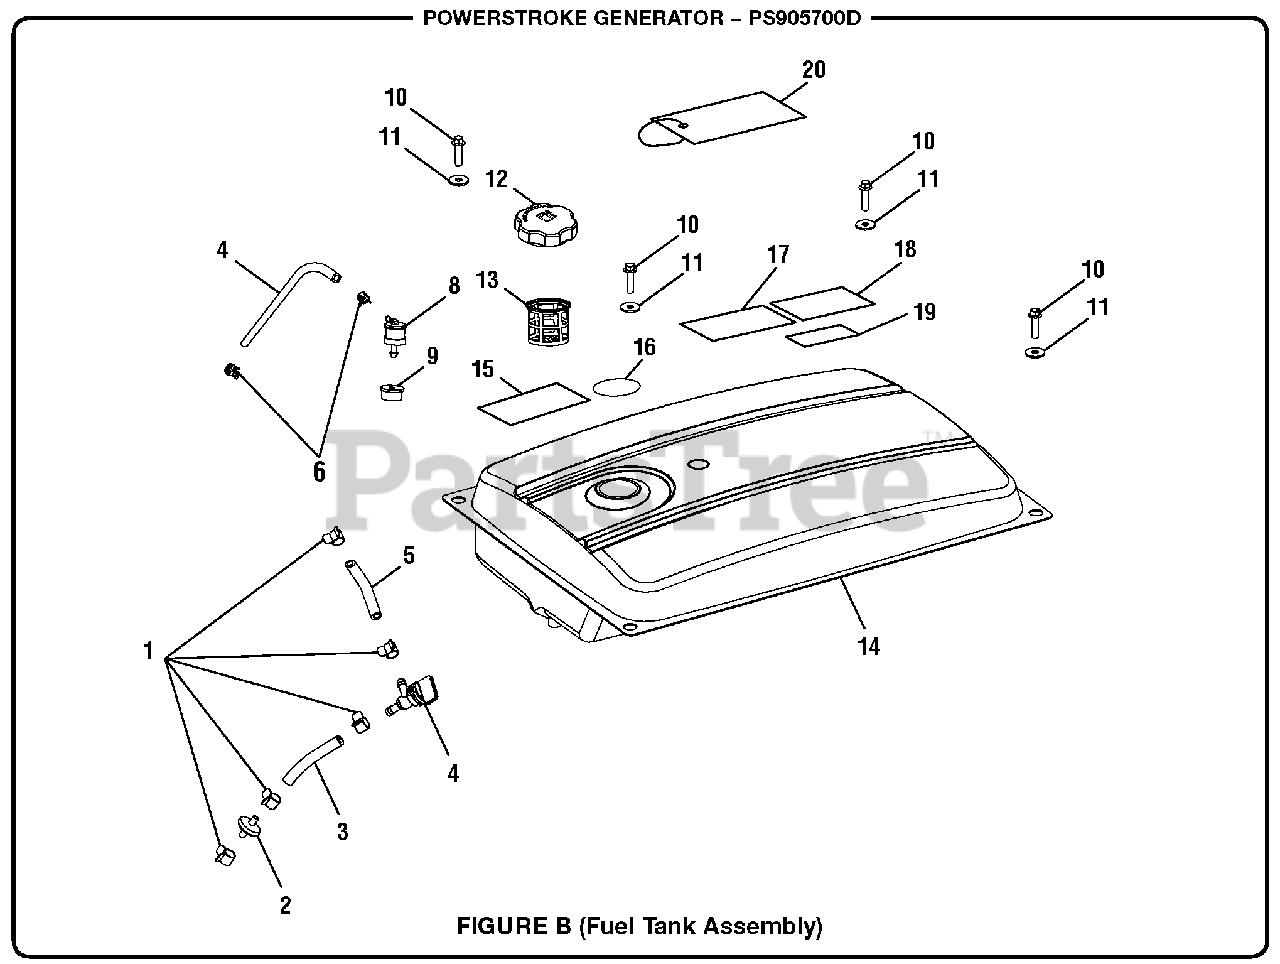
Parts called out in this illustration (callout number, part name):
1	Fuel Line Clip
2	Fuel Line Filter
6	Fuel Line Clip
9	Packing Washer
12	Fuel Tank Cap
13	Fuel Strainer
14	Fuel Tank
15	Fuel Stabilizer Label (Sp.)
16	Fuel Stabilizer Label
17	Danger Label
18	CPSC Label
19	E85 Label
20	Warning Hangtag
